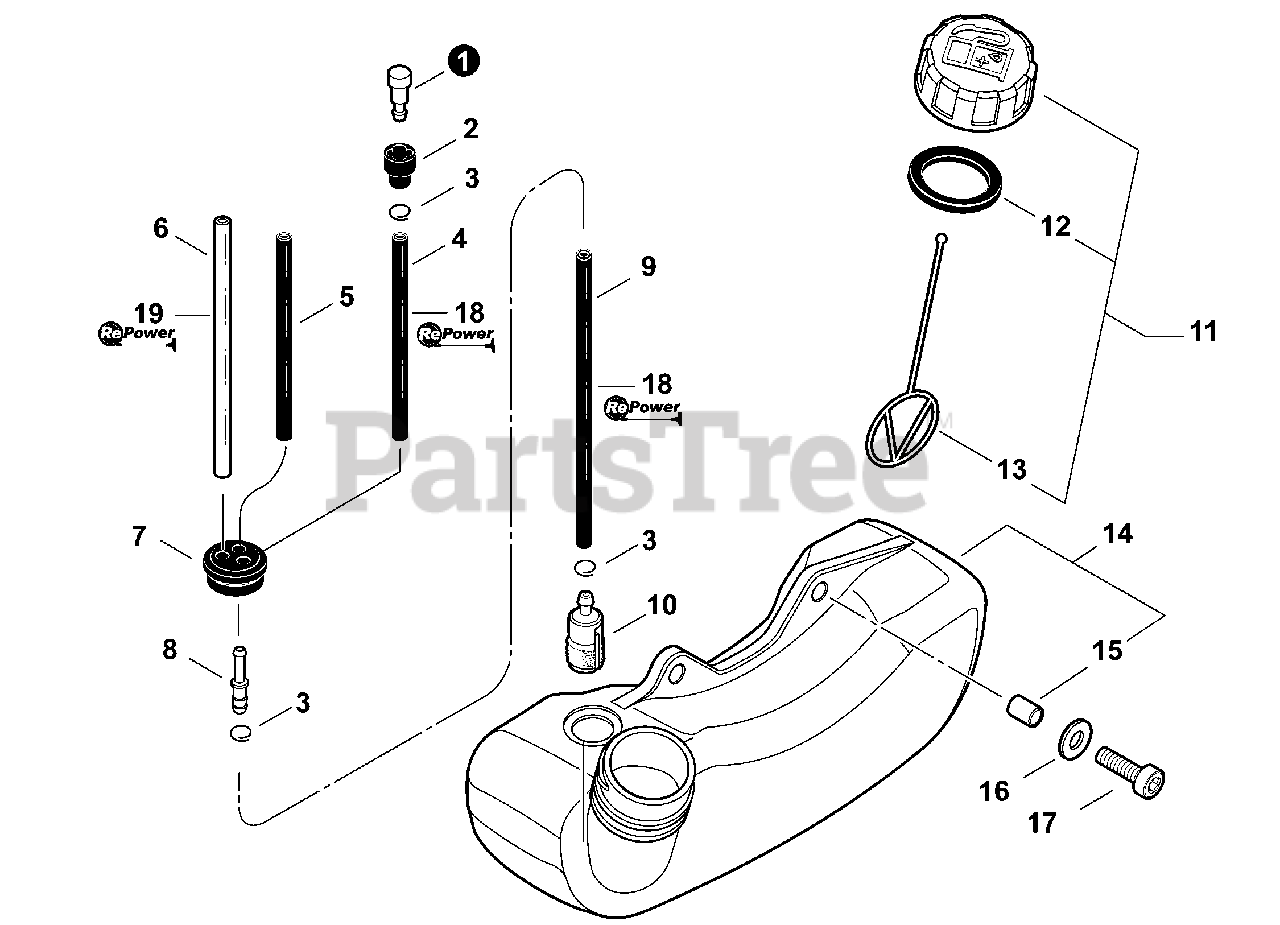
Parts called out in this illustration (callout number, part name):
1	VENT ASSY
2	HOLDER, VENT
3	CLIP Ø6
4	PIPE, FUEL 3x-5x-70 BLACK
5	PIPE, FUEL 3×5×87 BLACK
6	PIPE, FUEL RETURN 3×6×90 MM CLEAR
7	GROMMET, FUEL Ø5
8	CONNECTOR, PIPE Ø5ר3.5
9	PIPE, FUEL 3×5×130 BLACK
10	FILTER, FUEL
11	CAP ASSY, FUEL
12	GASKET, FUEL CAP
13	CONNECTOR, CAP L= 100 MM
14	TANK ASSY, FUEL
15	SPACER 6.2×7.8×6
16	WASHER 5.5×12×0.8
17	BOLT 5×16
18	BULK PIPE - 3×5 MM BLACK (4 PIECES×2 M)
19	BULK PIPE - 3×6 MM CLEAR (4 PIECES×2 M)
